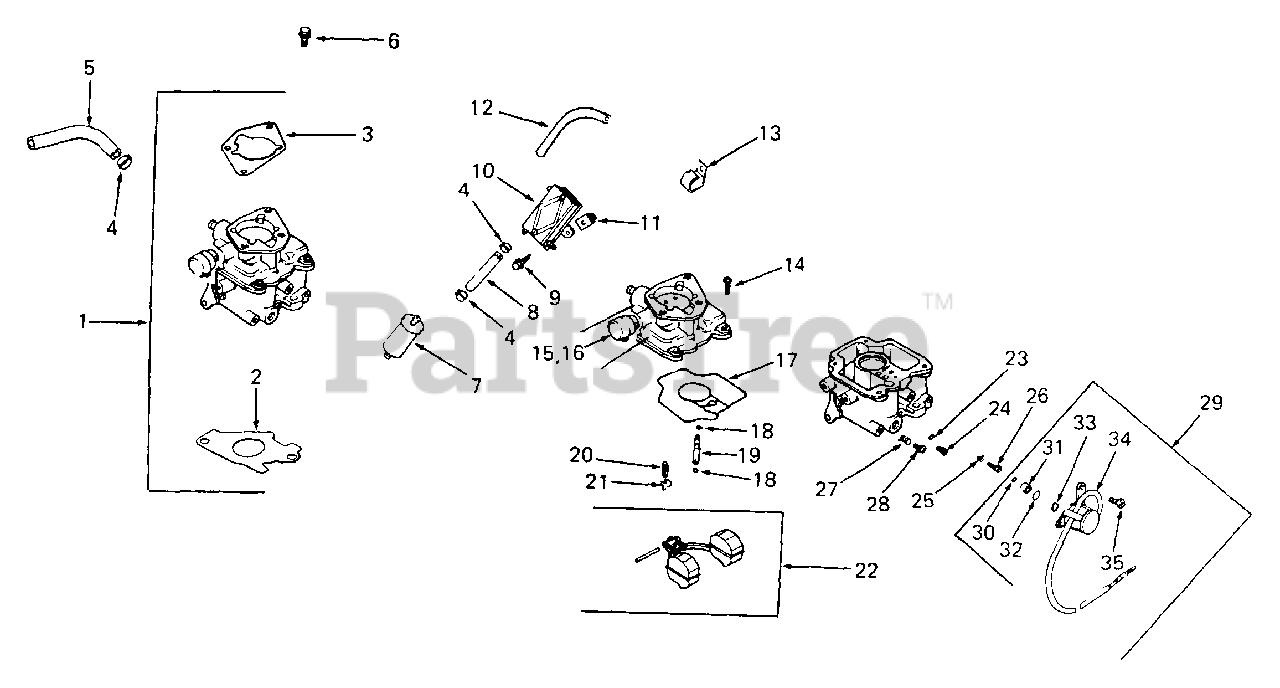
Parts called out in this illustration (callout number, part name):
1	Kit, Carburetor
2	Gasket, Carburetor
3	Gasket, Air Cleaner
4	Clamp, Hose
5	Line, Fuel, 15-1/2"
6	Screw, M6 x 1.0 x 18
7	Filter, Fuel
8	Line, Fuel, 9"
9	Screw, Hex Cap
10	Pump, Fuel-Pulse
11	Nut, Plastic
12	Line, Fuel, 10"
13	Clip, Cable
14	Screw, Carburetor Body
15	Kit, Choke Repair
16	Cap, Choke Lever
17	Gasket, Carburetor Body
18	O-Ring, Slow Jet
20	Valve, Inlet Needle
21	Clip, Inlet Needle Valve
22	Kit, Float Repair
23	O-Ring, Main Jet
25	Spring, Idle Adjust
26	Needle, Idle Adjust
27	Spring, Idle Speed Adjust
28	Screw, Idle Speed Adjust
29	Kit, Solenoid Assy
30	O-Ring, Solenoid
31	Seat, Solenoid
32	O-Ring, Solenoid
33	O-Ring, Solenoid
34	Solenoid
35	Screw, Solenoid
